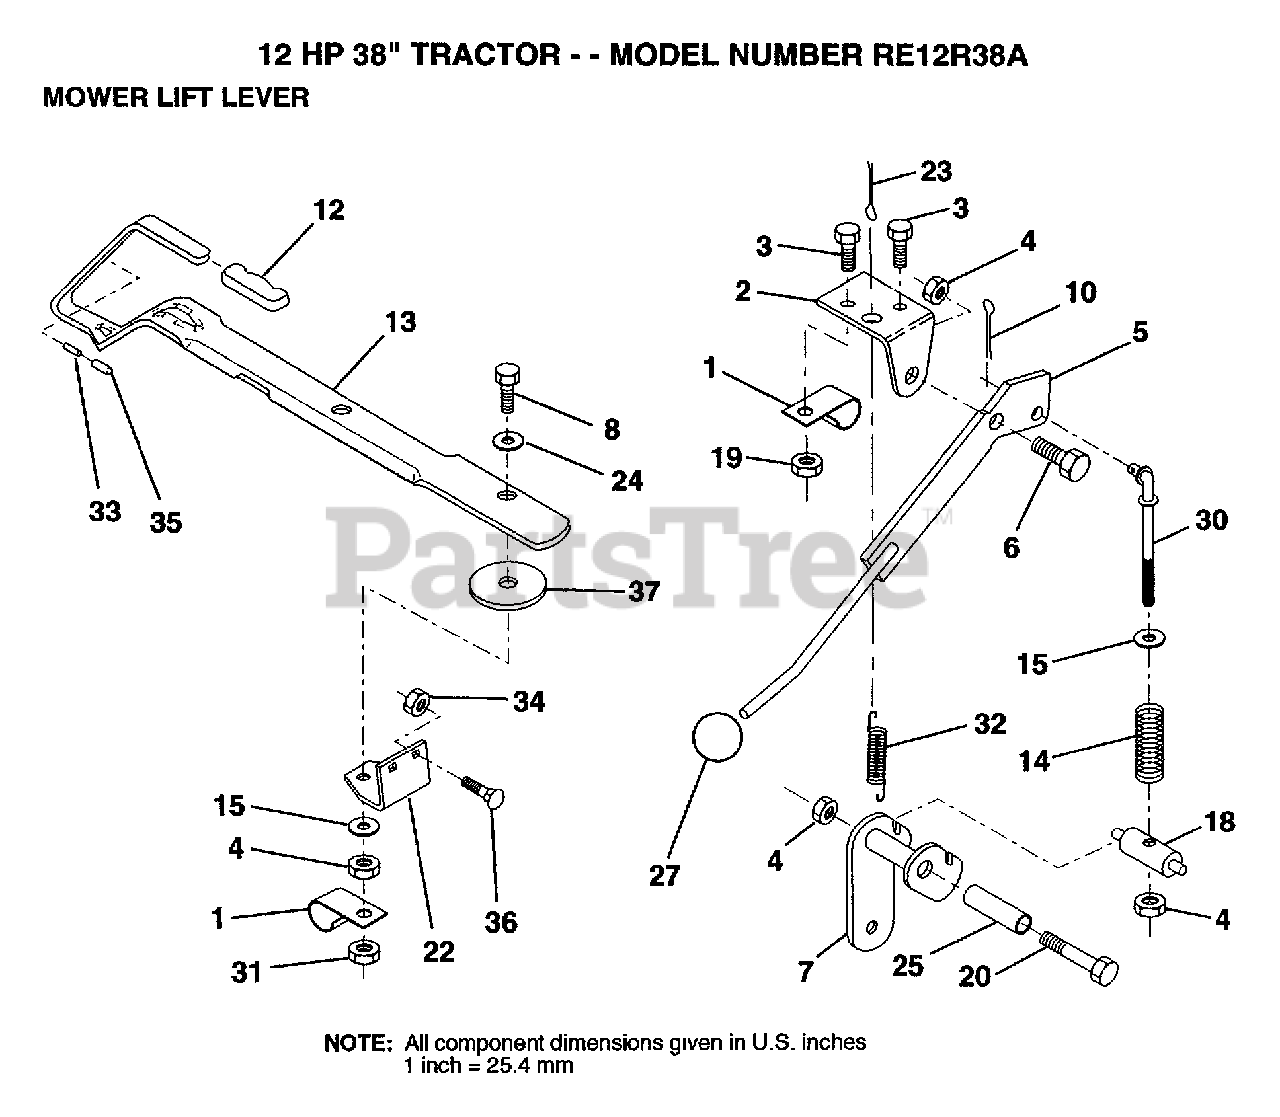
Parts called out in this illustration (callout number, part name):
1	CLIP,INSULATOR
2	BRKT CLUTCH
3	BOLT
5	CLUTCH LEVER AS
6	BOLT, SHOULDER LT
7	MWR CLUT ARM ASM
8	BOLT
12	LIFT LEVER HANDLE
13	LIFT HANDLE ASM
14	COMP CLUTCH SPRNG
15	WASHER HYT
18	TRUNNION
20	BOLT
22	LIFT LEVER BRKT
27	KNOB
30	ROD TENSION CLUTC
31	LOCKNUT
32	SPRING EXT
33	ROLL PIN
35	VINYL CAP RED
36	BOLT
37	WASHER T
